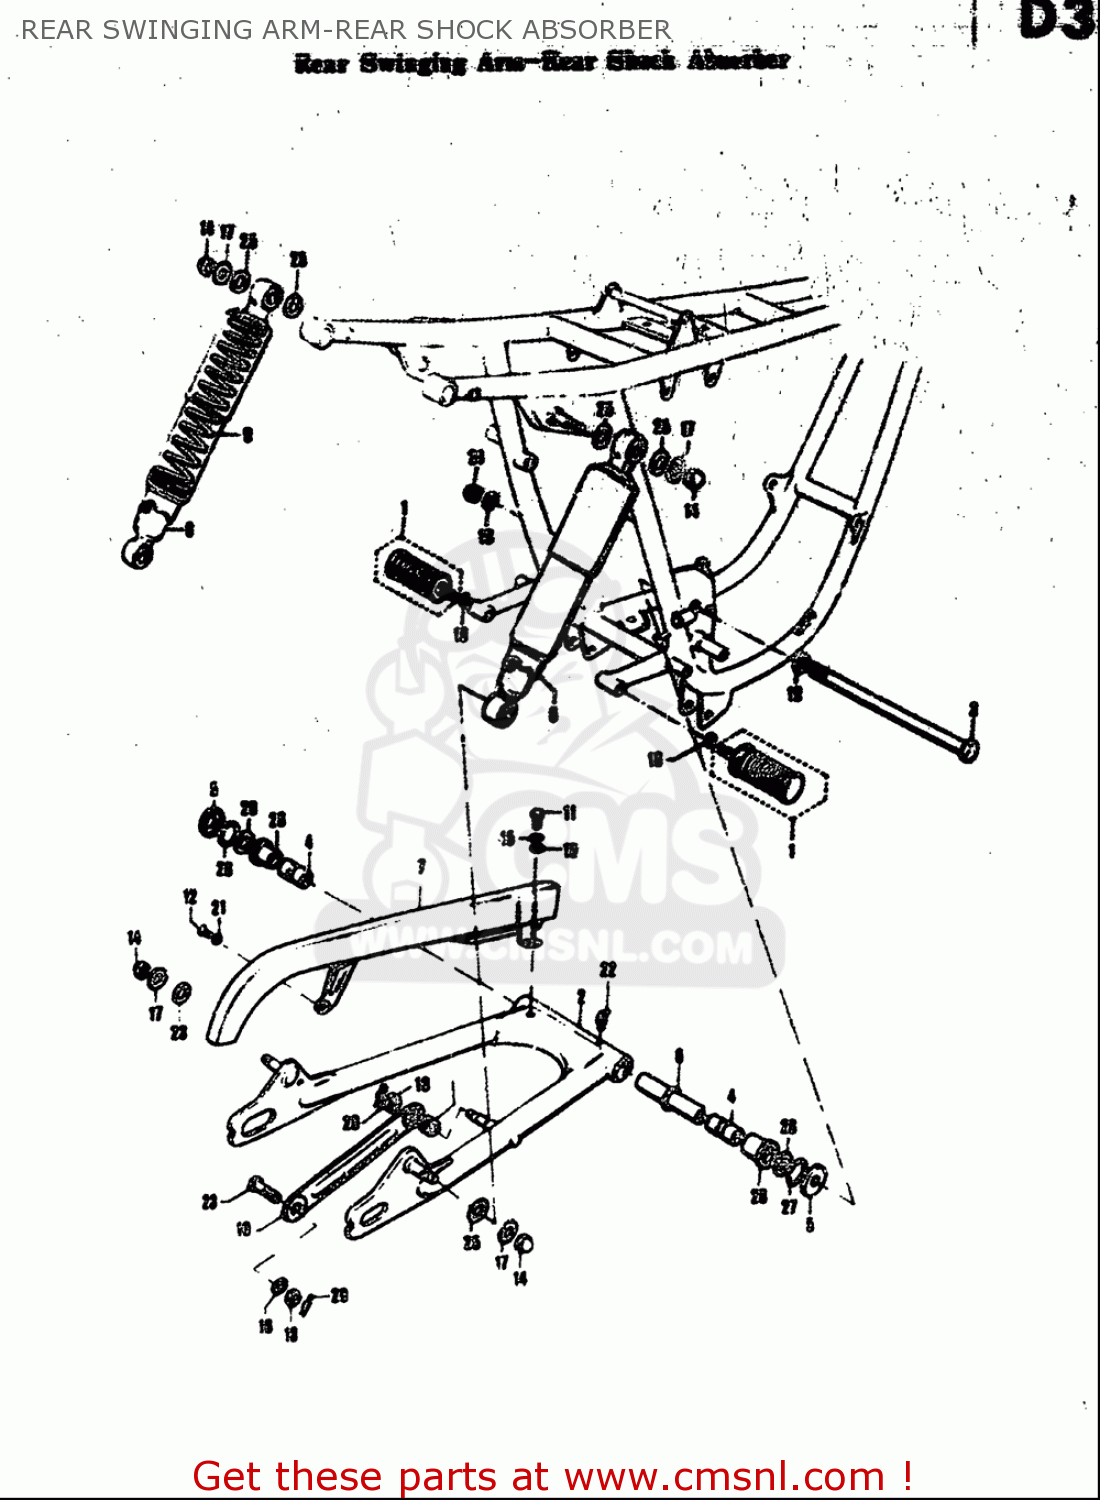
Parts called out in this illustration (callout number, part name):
1	FOOTREST SET,PILLION
4	SPACER
5	COVER
13	NUT
14	NUT
15	WASHER,LOCK
16	WASHER,LOCK
17	WASHER
18	WASHER
19	WASHER
20	WASHER
21	TOOTHED WASHER
22	NIPPLE,GREASE
23	BOLT(10X31)
25	WASHER (10.5X24X2.3)
26	WASHER(14.5X29X2.3)
27	O RING(D:3,ID:29.5)
29	CLIP
30	SPRING
